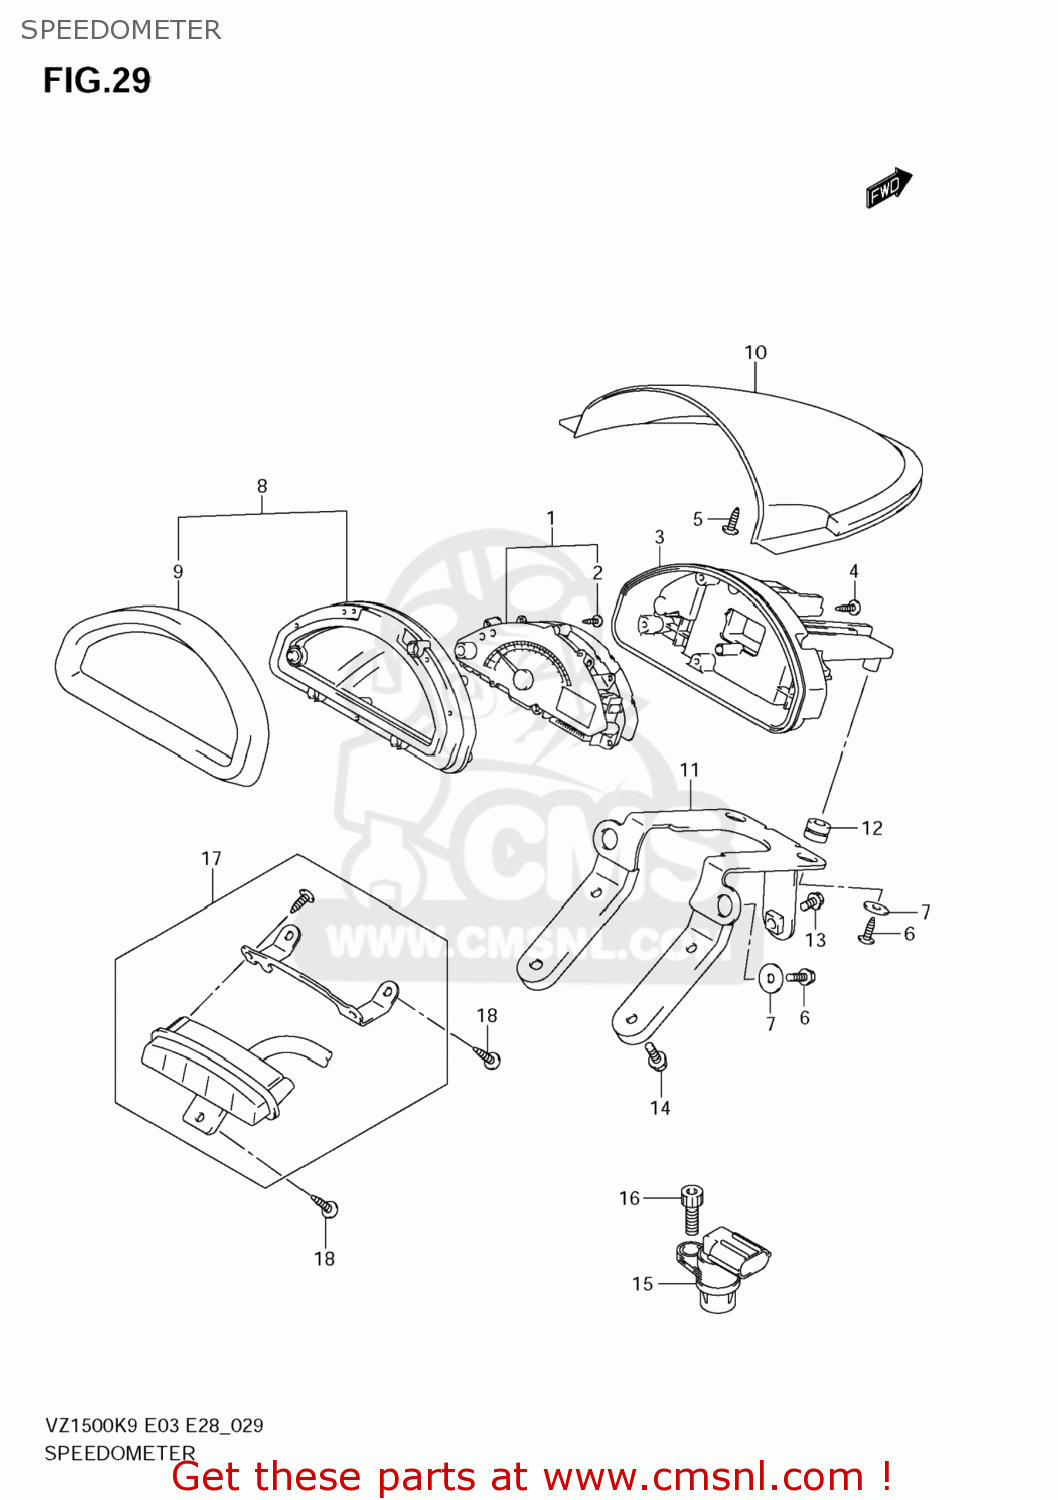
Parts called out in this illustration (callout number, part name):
1	COMBINATION METER
2	SCREW(3X14)
3	LWR CASE
4	SCREW(3X14)
5	SCREW(4X14)
6	SCREW(5X16)
7	WASHER(5.2X20X1.0)
8	UPR CASE
9	UPR COVER
10	LWR COVER
11	BRACKET
12	DAMPER
13	BOLT
14	BOLT
15	SENSOR COMP,SP
16	BOLT
17	BOX ASSY,PILOT LAMP
18	SCREW
